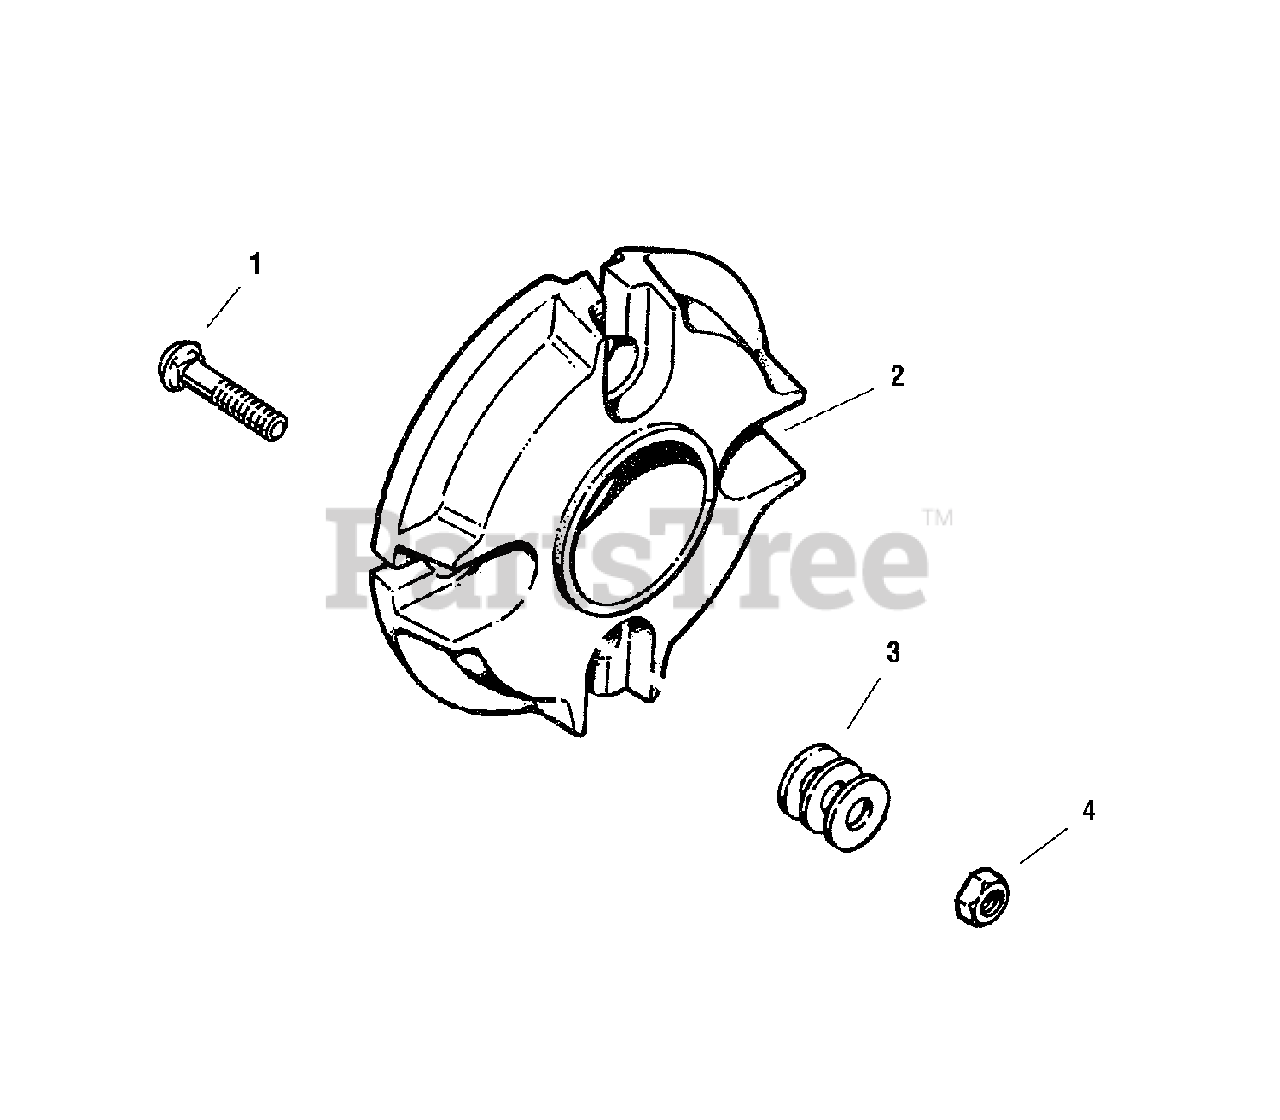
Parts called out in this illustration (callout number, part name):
1	CARRIAGE BOLT
2	WHEEL WEIGHT
3	PLAIN WASHER 1/2"
4	HEX NUT, Full Lock, 1/2-13"
